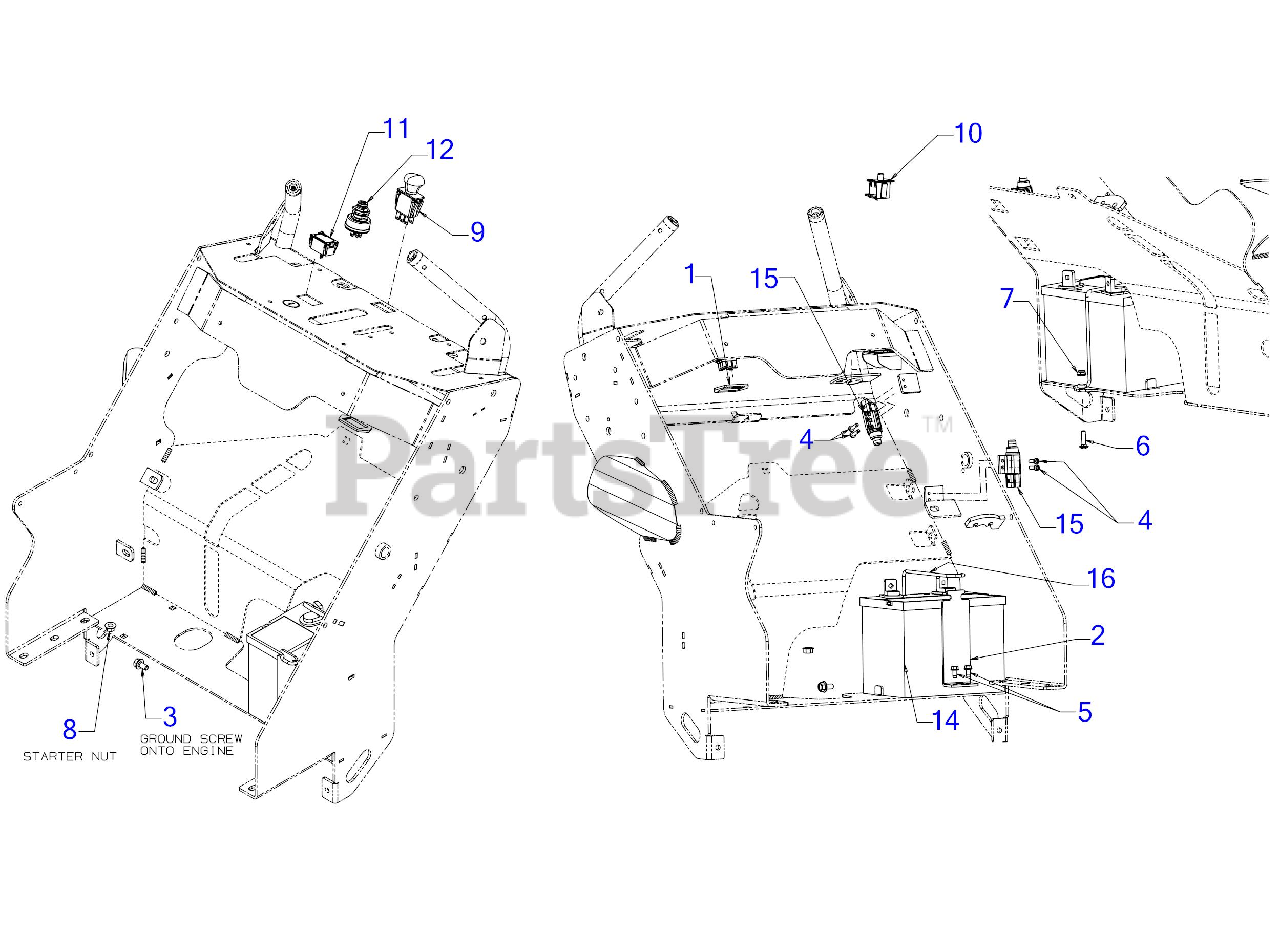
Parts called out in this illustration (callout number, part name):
1	BRACKET-PTO SWITCH
2	BATTERY RETAINING BRACKET
3	SCREW M8 x 1.25 x 16MM GR8.8
4	SCREW (10-24X.75:PH:TAP:T25:GR5)
5	SCREW 1/4-20 X.500
6	SCREW 1/4-20 x 1 GR5
7	FLANGE LOCK NUT
8	HEX FLANGE NUT M8X
9	PTO SWITCH (BLACK KNOB) TEXT SYM
10	SEAT SWITCH
12	KEY SWITCH (3 POSITION) (Add 925-06908)
13	WIRE HARNESS
14	Purchase Battery Locally
15	SEALED PLUNGER SWITCH
16	BATTERY SUPPORT ROD
